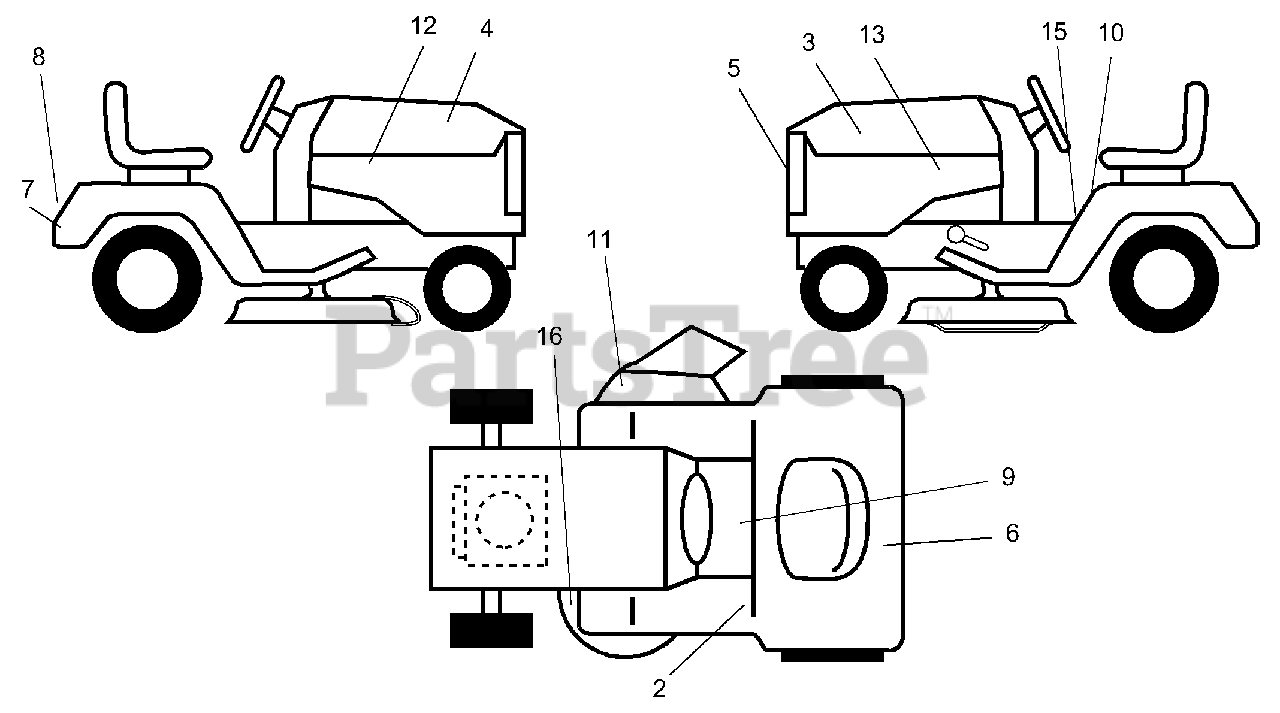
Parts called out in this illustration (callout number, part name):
2	Decal Indicator Height
3	Decal, Hood, L.H.
4	Decal, Hood, R.H.
5	Decal, Logo, Grill
6	Decal, Caution Battery
7	Decal, Drawbar
8	Decal, Logo, Fender
9	Decal, Cold Start
10	Decal, Fender, Caution
11	Decal, Warning, Multi-Language
12	Decal, Hood, Insert, R.H.
13	Decal, Hood, Insert, L.H.
15	Decal, Instruction, Operating
16	Decal, V-Belt Schematic
CR38	Grass Catcher
MK380	Mulcher Kit
